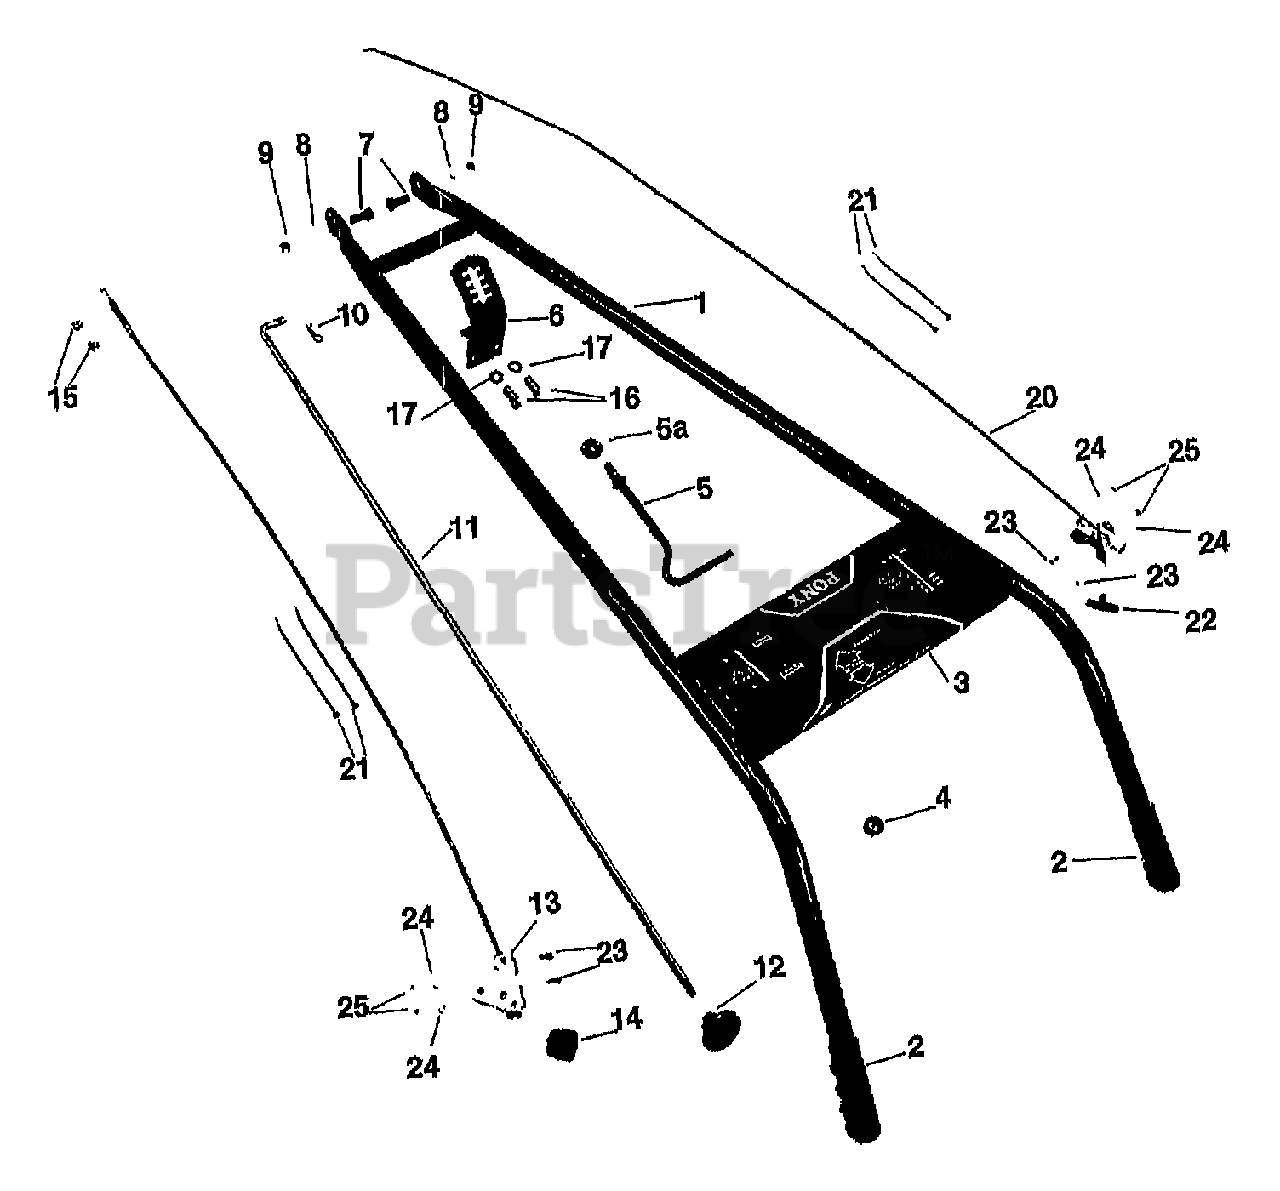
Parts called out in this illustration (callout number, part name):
1	ASSM-HANDLEBAR P4 (INCL. 2-5A)
2	GRIP-HANDLEBAR
3	DECAL-CONTROL PANEL
4	GROMMET-PLASTIC (PART OF OPERATOR CONTROL PANEL)
5	ASSM-STUD H/B
5A	WASHER-1.0X.38X.375
6	PLATE-HANDLEBAR ADJUST
7	SCR-HH 3/8-16X1.0 G5
8	WASHER-FLAT 3/8 SAE (HANDLBAR ATTACHMENT)
9	NUT-LOCK 3/8-16 NYLON (HANDLBAR ATTACHMENT)
10	PIN-CLIP .08
11	ASSM-DR CONTROL ROD - COMPLETE (INCL. KNOB, #9208)
11	ROD-CONTROL (#9208 KNOB, NOT INCL.)
12	KNOB-DRIVE CNTRL ROD
13	KIT-WHL DRIVE CABLE - COMPLETE (INCL. 14,15, 21,23,24,25)
14	KNOB-WHEEL DRIVE CABLE
15	NUT-HEX 5/16-24
16	SCR-HH 3/8-16X.75 G5
17	WASHER-LK .375
20	CABLE-THROTTLE - COMPLETE (INCL.22) (DOES NOT INCL. 23-25)
21	TIE-RED (PLASTIC)
22	KNOB-THROTTLE CABLE
23	SCR-RH M10-32X.5 MACH
24	WASHER-LK M10
25	NUT-HH M10-32X.125
